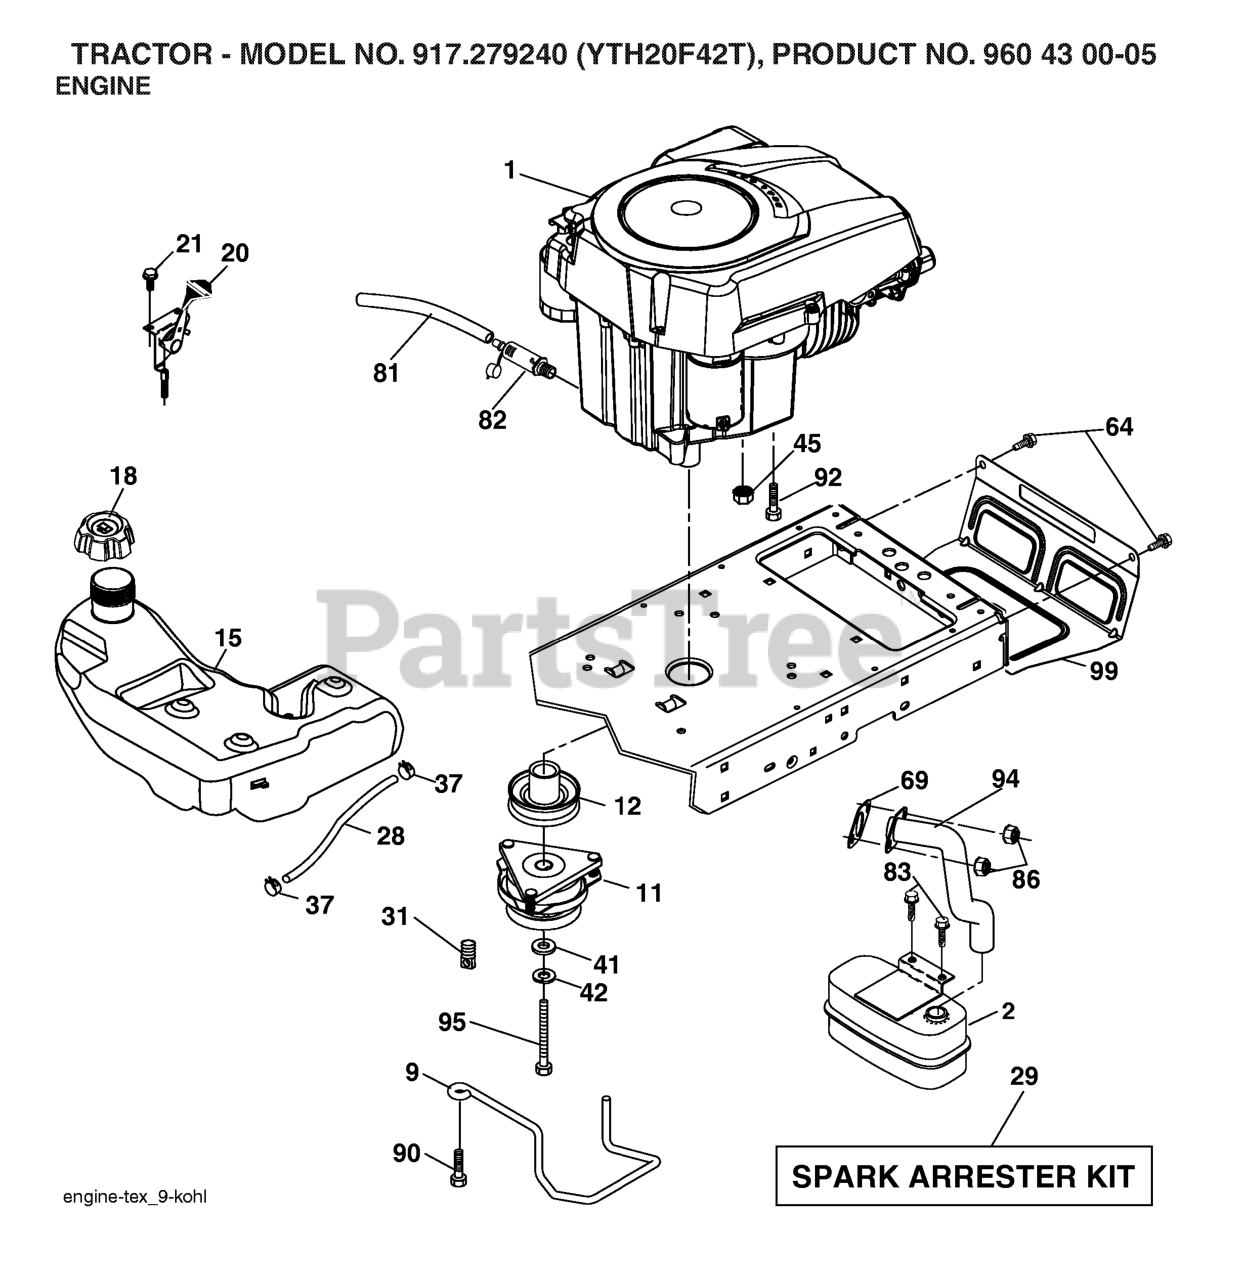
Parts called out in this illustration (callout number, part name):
2	MUFFLER.SINGLE.CYL.KOHL/B&S
9	KEEPER.BELT.ENGINE.3.25 (3 2)
11	RB.CLUTCH.OGURA.4.4.PD
12	PULLEY.ASM.ENG.OGURA.3
15	TANK.FUEL.4GAL
18	CAP.FUEL.TANK.3"GREY
20	CONTROL.TH/CK.COBRA.KO
21	SCREW
28	LINE.FUEL.64"REAR.EMIS
29	KIT.SPARK ARRESTOR 794945 B&S
31	DECAL BTRY SYMBOLS
37	HOSE CLAMP
42	LOCKWASHER
45	NUT
64	SCREW, 3/8-16X3/4
69	GASKET.EXHAUST.KOHLER
81	TUBE, DRAIN OIL ASM.
82	PLUG DRAIN OIL EASY
83	BOLT.5/16-18UNCX3/4 W/SEMS.BLK
86	NUT.HEX.FLANGE.TOPLOCK
90	SCREW 3/8-16X1
92	SCREW 3/8-16X1
94	RP.TUBE.EXHAUST.KOHL.COURAGE
95	BOLT HEX 7/16-20X4-1/4"
99	SHIELD.BROWNING/DEBRIS
